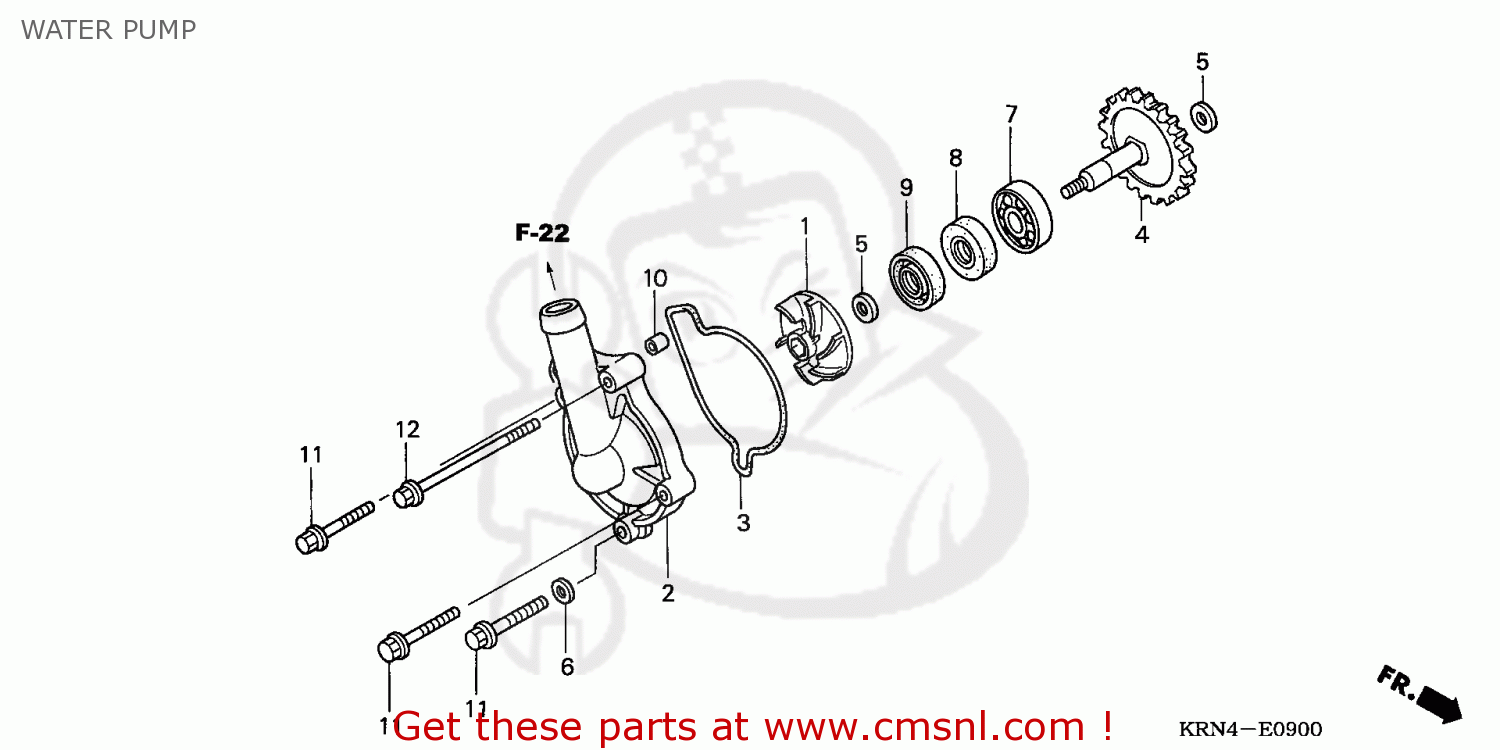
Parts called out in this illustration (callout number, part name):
1	IMPELLER,W/P
2	COVER,WATER PUMP
3	GASKET,WATER PUMP
4	GEAR COMP,WATER P
5	WASH,SEALING,7MM
6	WASHER,SEALING,6.
7	B/BRG RAD N/COM
8	OIL SEAL,12X22X5
9	SEAL,WATER PUMP
10	DOWEL,PIN,8X10
11	BOLT,FLANGE,6X28
12	BOLT,FLANGE,6X70
